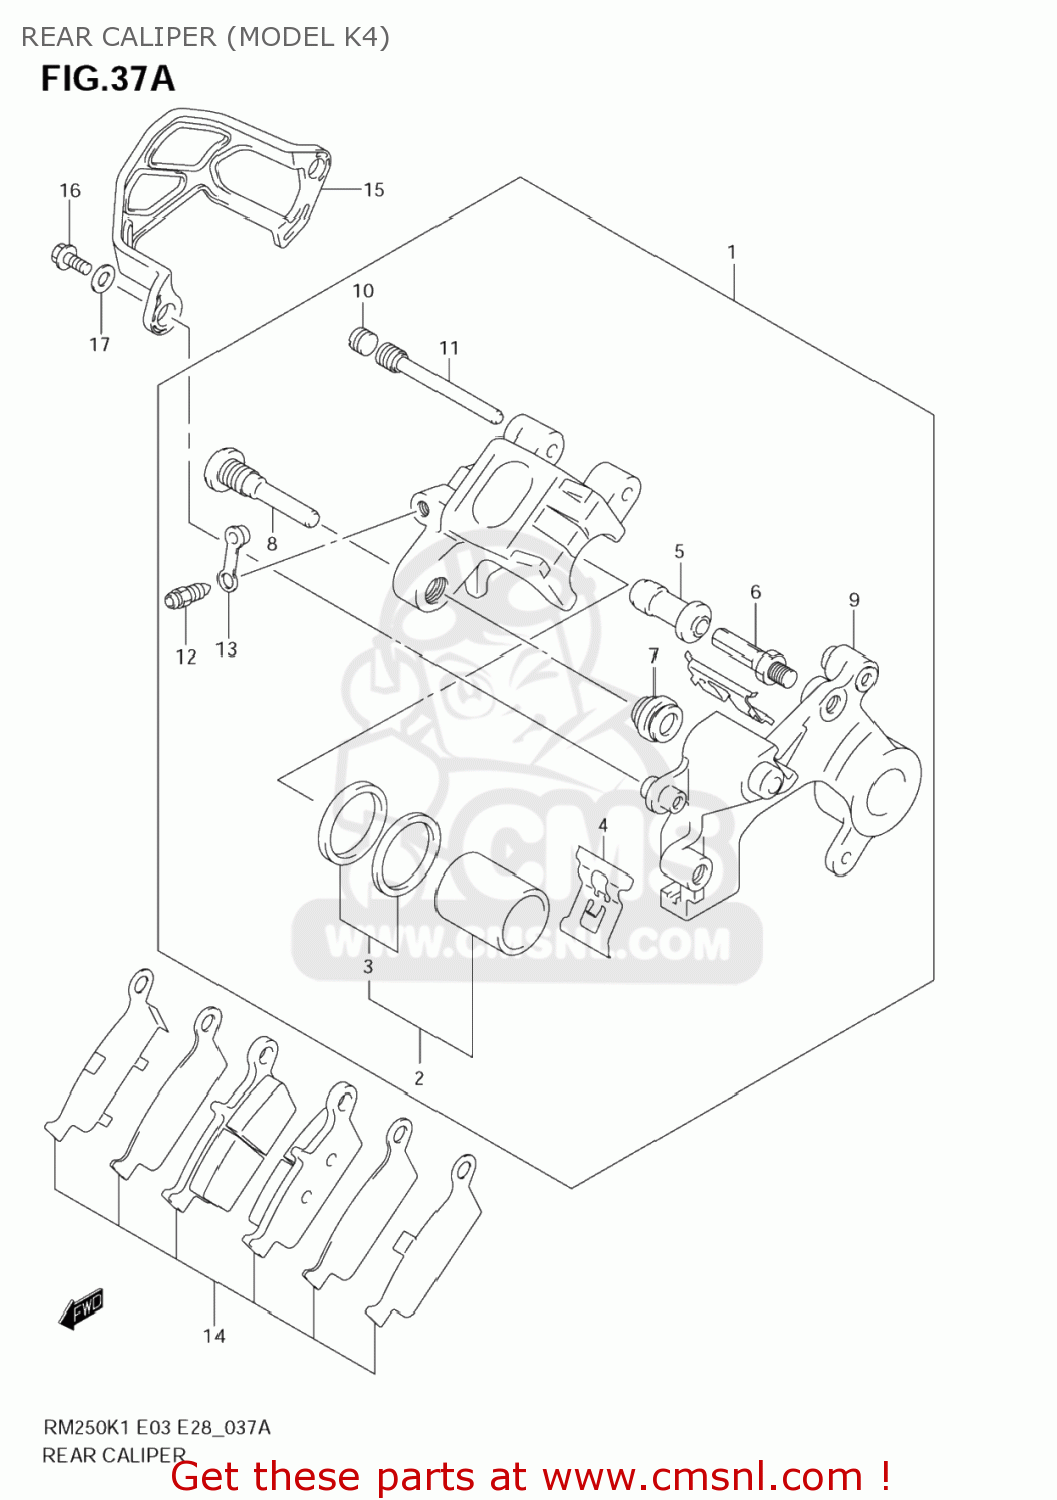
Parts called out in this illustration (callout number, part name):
1	CALIPER ASSY,RR
2	PISTON SET
3	SEAL SET,PISTON
4	SPRING,PAD
5	BOOT
6	BOLT
7	BOOT
8	PIN,BOLT
9	BRACKET
10	PLUG,PIN
11	PIN,HANGER
12	BLEEDER
13	CAP,BLEEDER
14	PAD & RETAINER SET
15	GUARD,RR CALIPER
16	BOLT
17	WASHER
